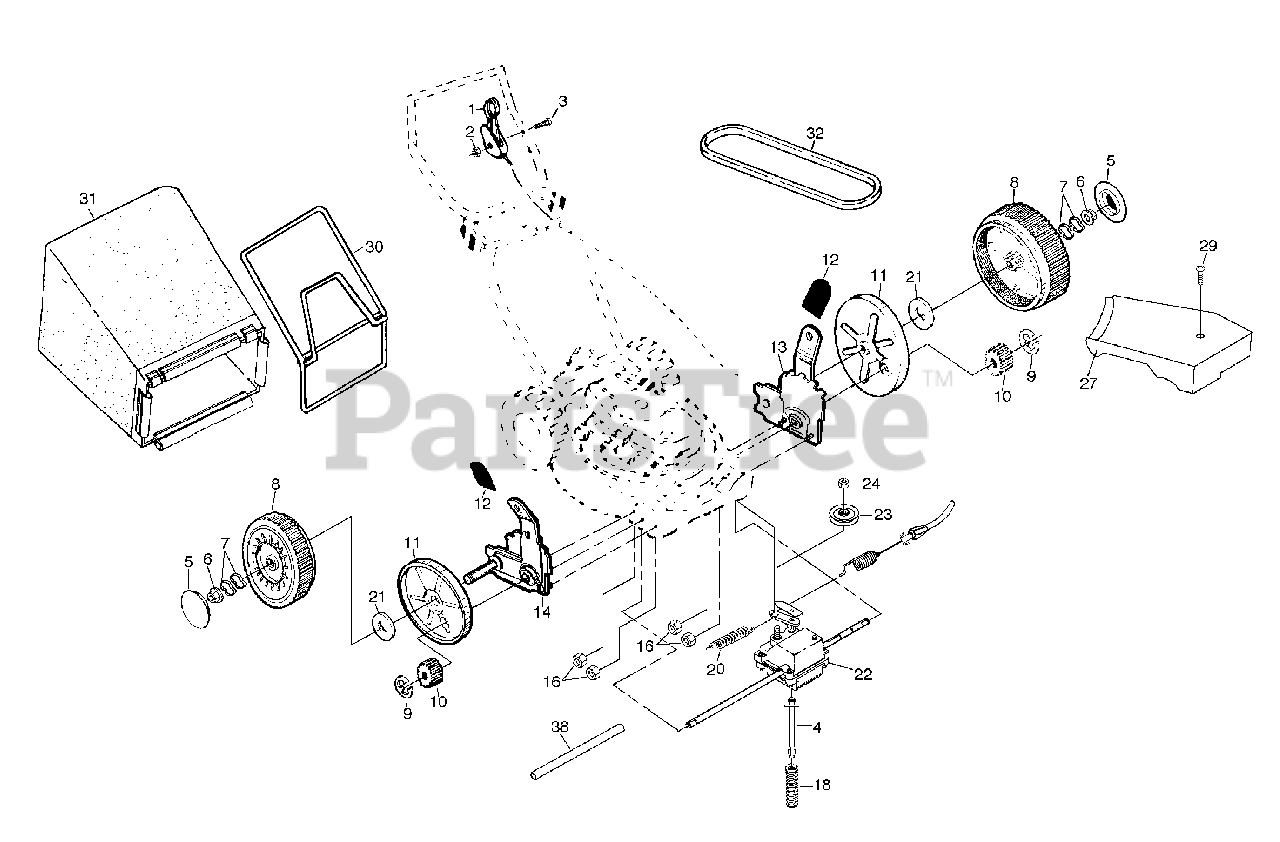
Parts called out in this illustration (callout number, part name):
1	Drive Control
2	Locknut #10-24
3	Pan Head Machine Screw 1/4-20 x 2-1/8
4	Spring Retainer
6	Nut
7	Wave Washer
8	Wheel & Tire Assembly
11	Dust Cover
12	Selector Knob
13	Wheel Adjuster Assembly (Left)
14	Wheel Adjuster Assembly (Right)
16	Locknut
21	Washer 1/2 x 1-1/2 x .134
22	Gear Case Assembly
23	Drive Pulley
24	Locknut
27	Drive Cover
29	Pan Head Tapping Screw #10-24 x 1-3/4
30	Catcher Frame
31	Grass Bag
32	V-Belt
38	Drive Shaft Cover
38	Drive Cover Decal
38	Ht. Adjuster Decal RH
38	Ht. Adjuster Decal LH
